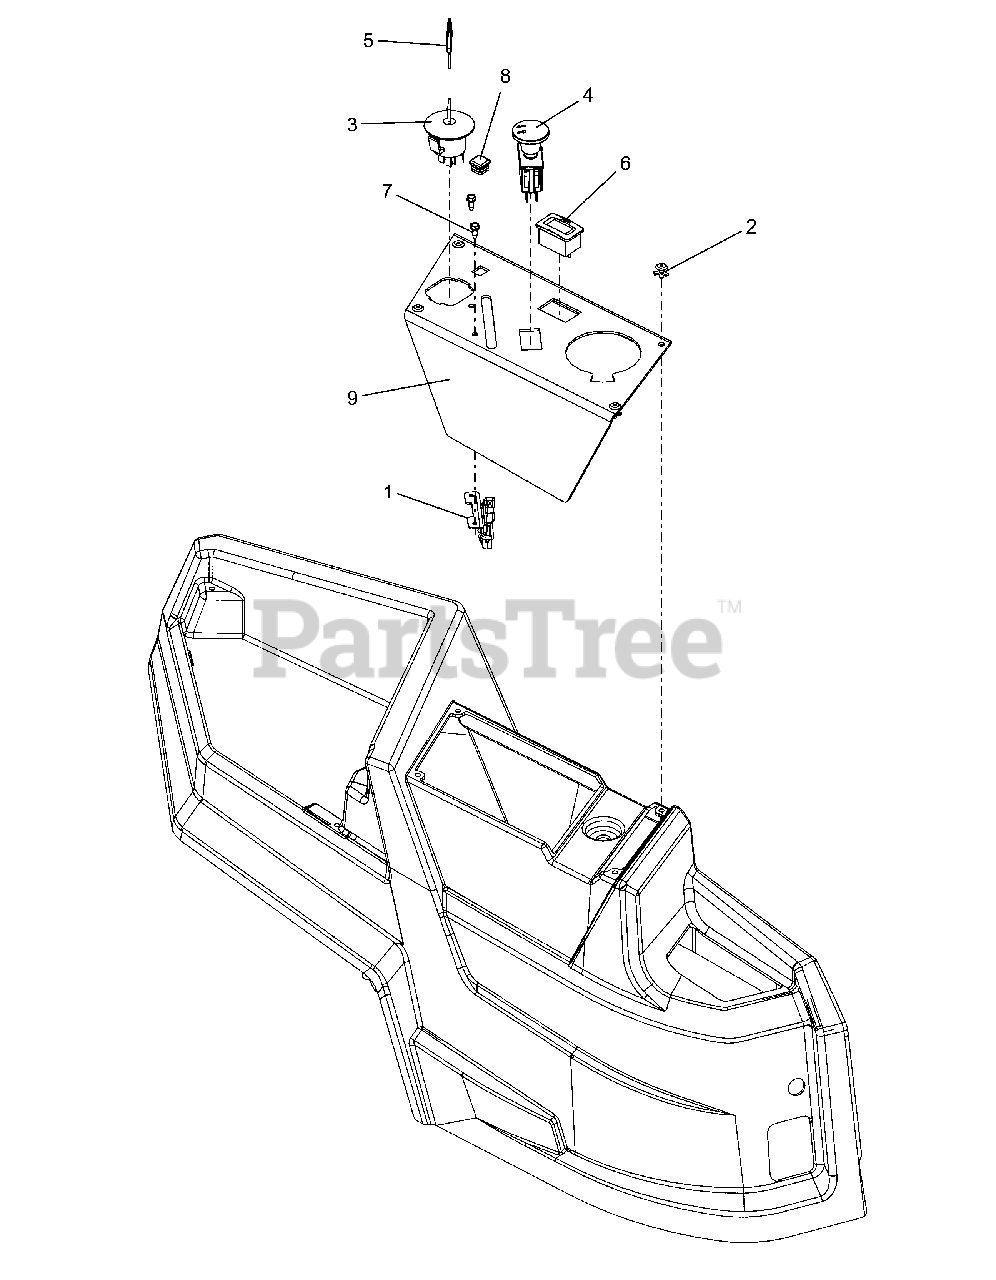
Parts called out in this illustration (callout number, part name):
1	CABLE - THROTTLE CONTROL
2	RIVET, PLASTIC .195 DIA.
3	KEYSWITCH-IGNITION 4 POS
4	SWITCH, CLUTCH (YELLOW)
5	KEY, IGNITION
6	HOUR METER
7	SCR,TAP #10-24X.50 HWH TR ZCC
8	PLUG, 5/8" SQ BLACK (14-20GA)
9	PANEL, CONTROL
